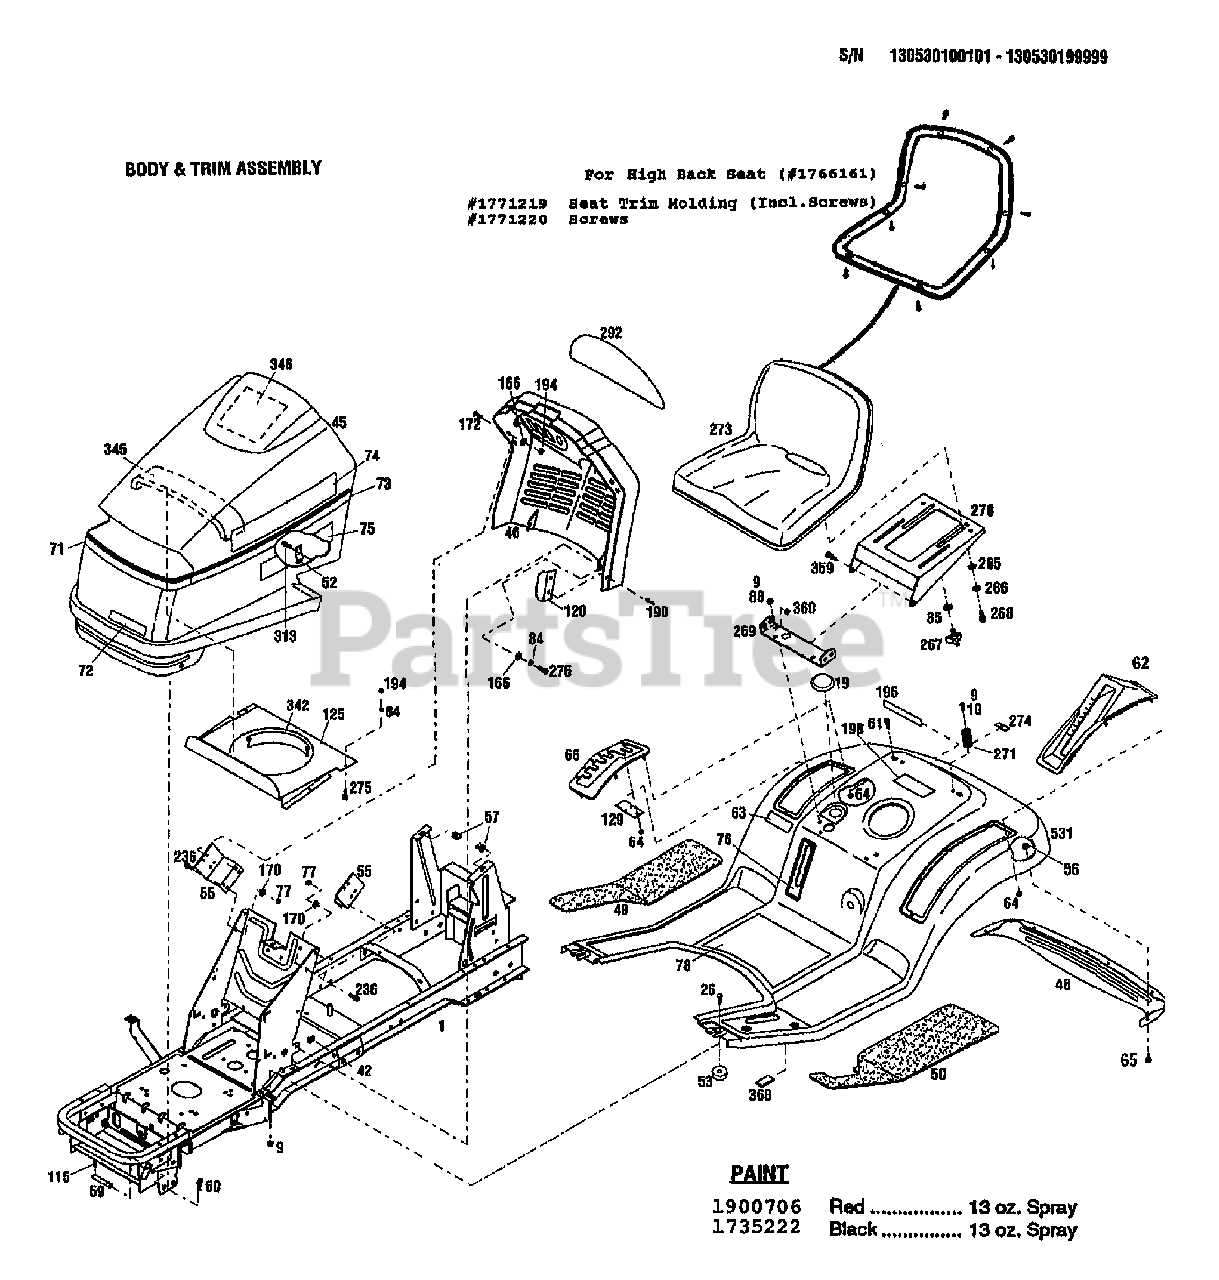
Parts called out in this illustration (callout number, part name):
9	NUT-HFLK 5/16-18 ZP
10	SCR-HHC 5/16-18X.75 GR 5 ZP
19	PLUG 2.50
26	SCR-CARR 5/16-18X1.0 G2 ZP
42	NUT-SPEED
45	HOOD-TRACTOR
46	CONSOLE
48	TRIM-FENDER REAR
49	PAD-FOOT RH
50	PAD-FOOT LH
52	LATCH
53	SPACER-TUBULAR
55	BRKT-MOUNTING
56	NUT-HF/LK 1/4-20 ZP
59	PIN-PIVOT HOOD
60	PIN-HITCH .125X2.56 ZP
61	SCR-LOCK
62	COVER-LIFT HANDLE
63	DECAL-AMERICAN LEGEND-LRG
64	NUT-SELF THRD 1/4
65	SCR-HH 1/4-20X.625
66	QUADRANT-SHIFT
71	DECAL-STRIPE HOOD FRONT
72	DECAL-LOGO
74	DECAL-LOGO TROY-BILT
75	DECAL-MODEL 13053
76	DECAL-FUEL LEVEL
77	NUT-HEX 5/16-18 ZP
78	DECAL-OPER INST
84	WASHER-LK .25 ZP
85	WASHER-FLAT 3/8 SAE
88	SCR-CARR 5/16-18X.62 G2 ZP
115	PIN-ROLL .188X1.0
120	BRKT-HOOD ALIGN
125	SHIELD-HEAT UPPER
129	SUPPORT-SHIFT ARM
166	WASHER-FLAT 1.25X.28X.062 ZP
170	WASHER-LK .312 ZP
190	RIVET-POP
194	NUT-HEX 1/4-20 ZP
196	DECAL-LOGO FENDER
198	DECAL-FUEL
236	SCR-HFLK 5/16-18X.75 ZP
265	WASHER-1.06X.51X.09 NYLON
266	WASHER-BOW .74X.52X.01
268	SCR-SHLDR 3/8-16X.25 G5ZP
269	BRKT-SUPPORT SEAT
270	SUPPORT-SEAT
271	SPRING-COMPRESSION
273	KIT-SEAT (TRACTOR)
274	BRKT-SPRING HOLD DOWN
275	SCR-HH 1/4-20X.625 G5 ZP
292	LENS-INSTRMTS WARN LIGHTS
342	GASKET-HEAT SHIELD
345	STRIP-SEALING
346	DECAL-SERVICE
359	SCR-HH 3/8-16X.88 G5 ZP
360	NUT-H/LK 3/8-16
531	FENDER-RED W/DECALS
